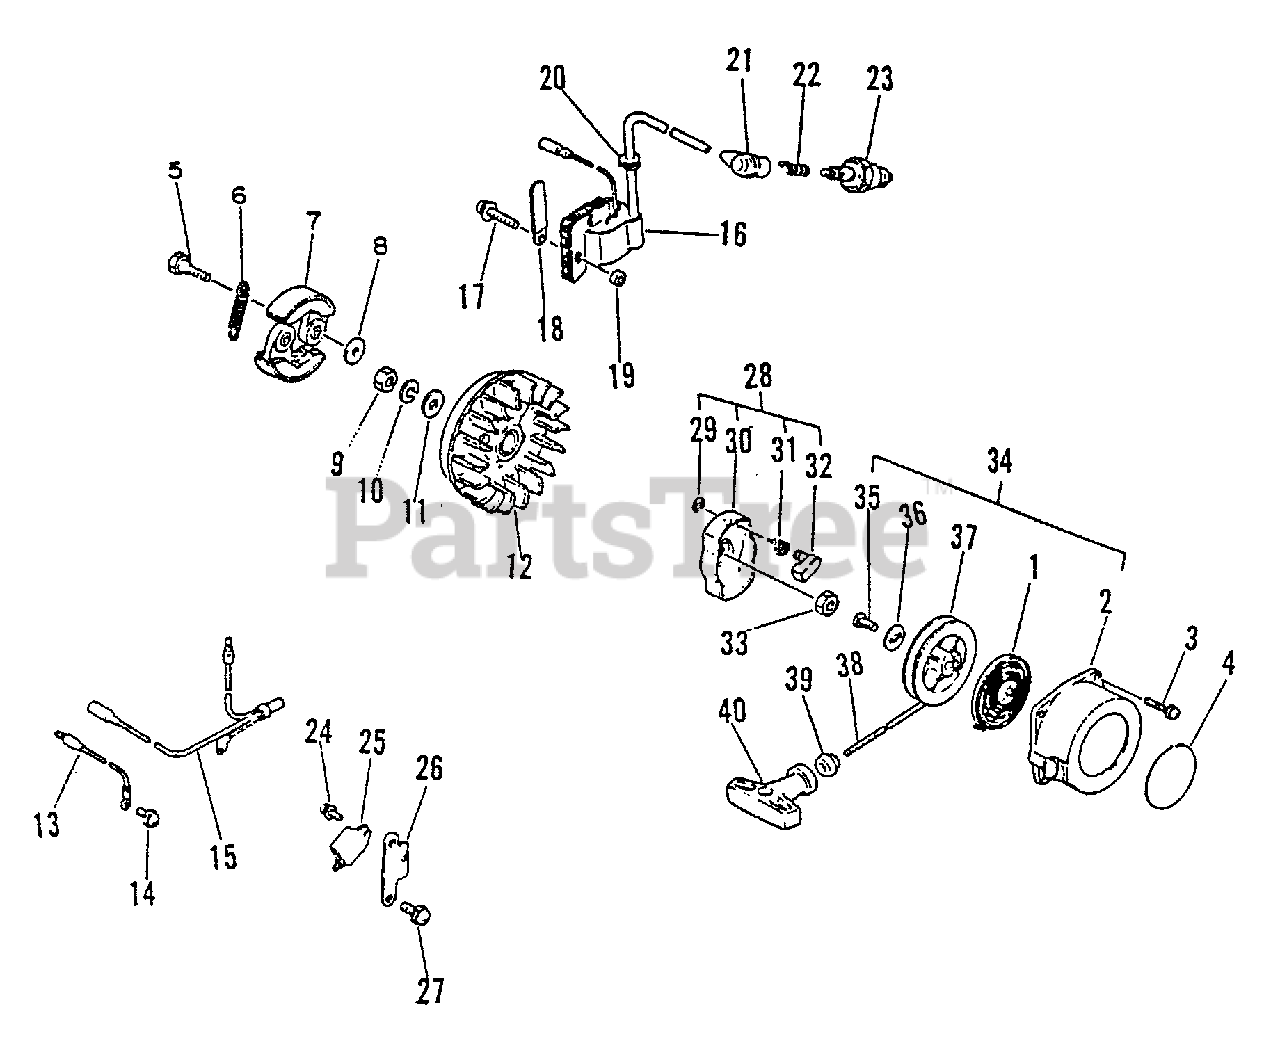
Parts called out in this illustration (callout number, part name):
1	SPRING, REWIND
2	CASE, STARTER - ORANGE
3	SCREW - 4X20
4	LABEL - ECHO
5	BOLT, CLUTCH
6	SPRING, CLUTCH
7	SHOE, CLUTCH
8	WASHER - 6
10	LOCKWASHER - 8
12	FLYWHEEL
13	LEAD - GROUND
14	SCREW - 5X10
16	COIL, IGNITION
17	SCREW - 5X25
19	SPACER
21	CAP, SPARK PLUG
22	TERMINAL, SPARK PLUG CAP
23	SPARK PLUG -- BPM-7A
24	SCREW - 4X8
25	COIL, IGNITION
26	BRACKET, IGNITION COIL
27	SCREW - 5X12
28	STARTER PAWL ASSY
29	RING, RETAINING - 4
30	CATCHER, PAWL
31	SPRING, RETURN
32	PAWL, STARTER
34	STARTER ASSY
37	REEL, ROPE
38	ROPE, STARTER - 4X880
39	GRIP, STARTER
40	GRIP, STARTER
